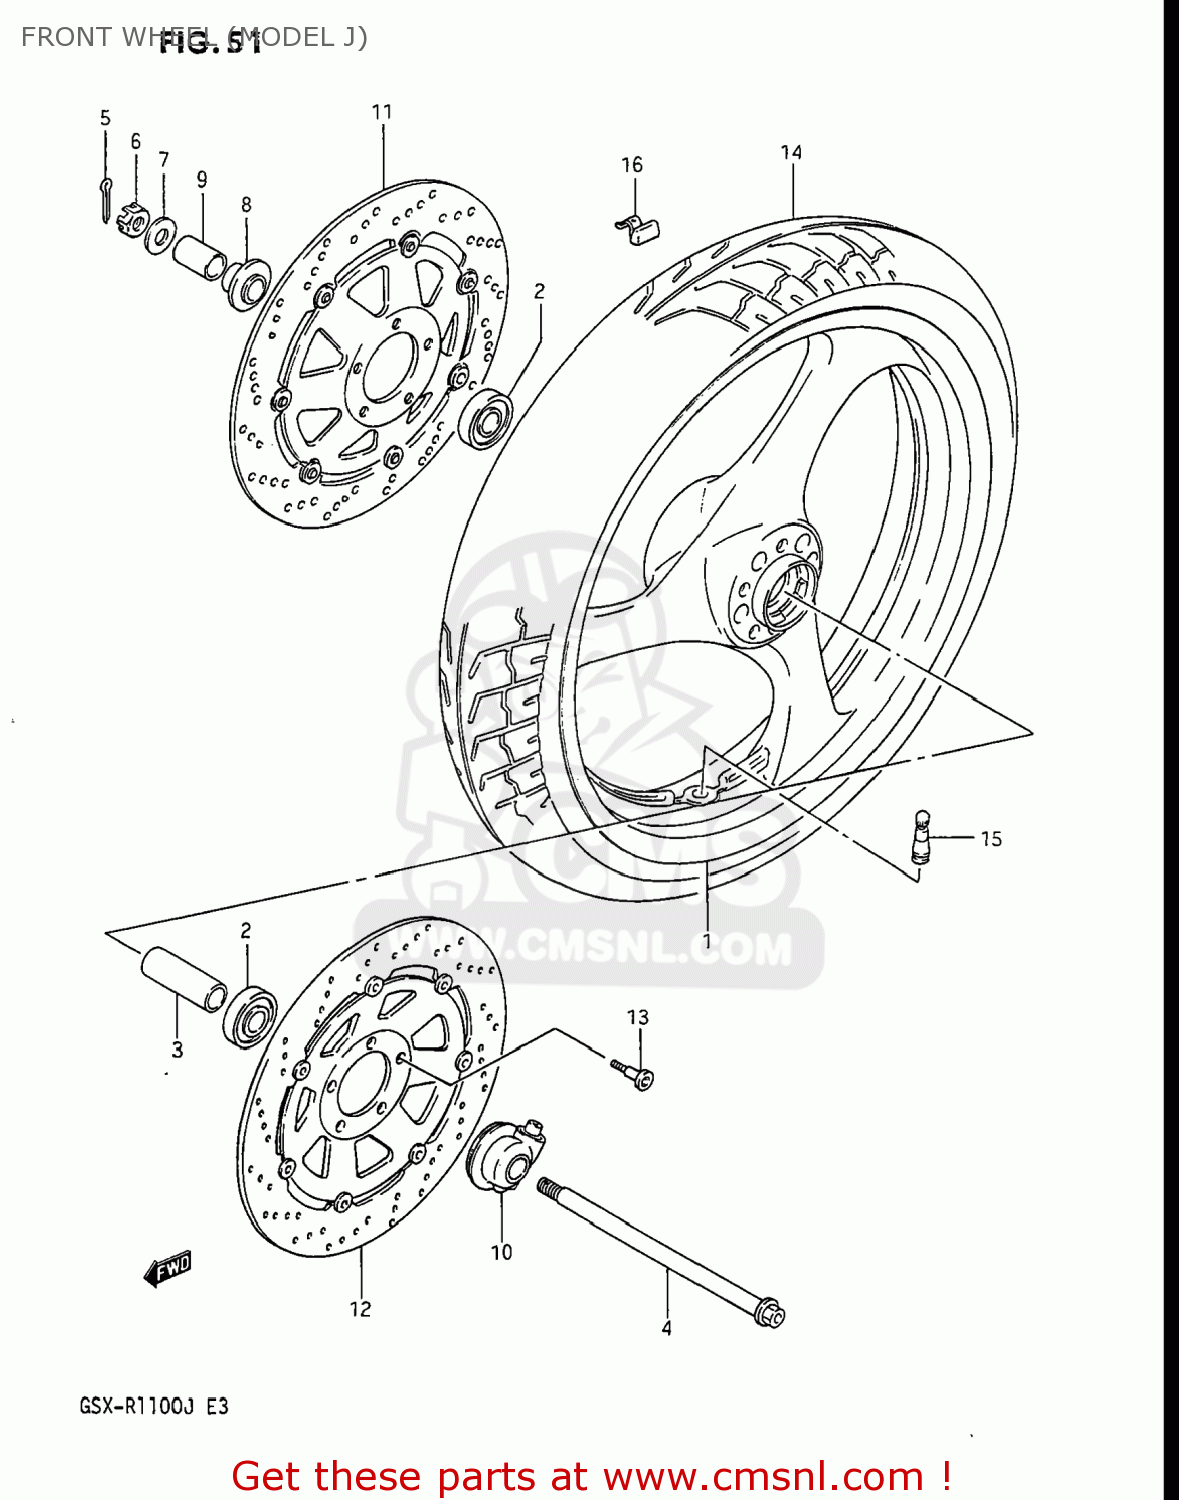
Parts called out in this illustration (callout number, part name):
1	WHEEL,FRONT (18XMT2.75)
2	BEARING
3	SPACER (17.3X24X76)
4	AXLE,FRONT
5	PIN,COTTER
6	NUT
7	WASHER
8	SPACER COMP,FRONT HUB
9	SPACER,FR AXLE
10	BOX ASSEMBLY,SPEEDOMETER GEAR
11	DISC,FR BRAKE,R
12	DISC,FR BRAKE,L
13	BOLT
14	TIRE,TUBELESS 110/80V
15	VALVE,TIRE
16	BALANCER,WHEEL
